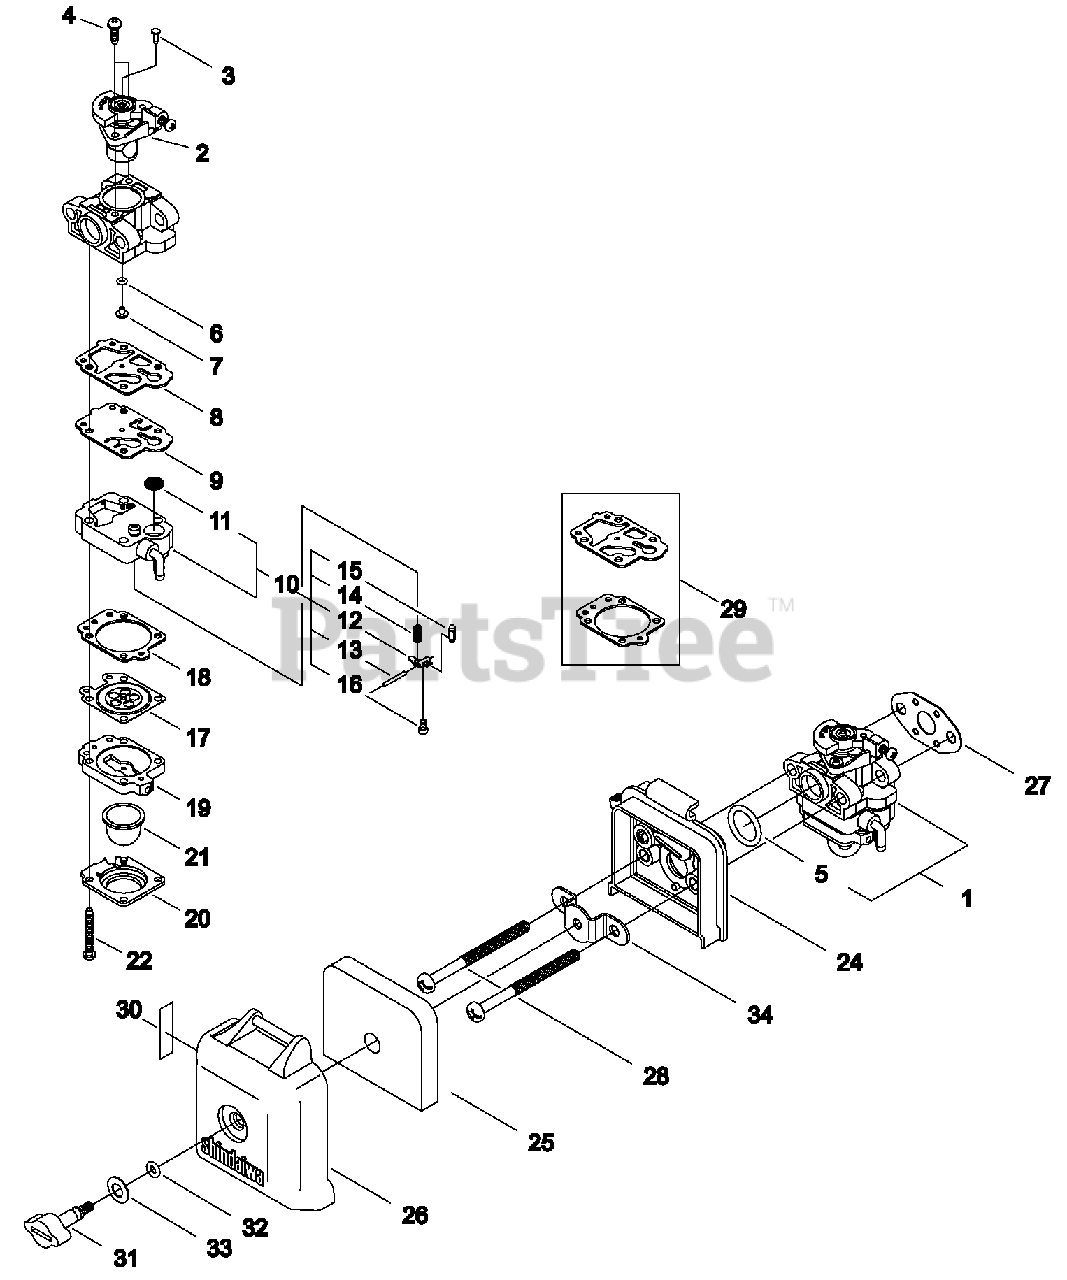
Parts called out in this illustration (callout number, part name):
1	CARBURETOR
2	VALVE ASSY, THROTTLE
3	PLUG
4	SCREW, THROTTLE COLLAR
5	O-RING 15
6	O-RING
7	JET, MAIN #40
8	GASKET, PUMP
9	DIAPHRAGM, FUEL PUMP
10	BODY ASSY, PUMP
11	SCREEN, FUEL INLET
12	LEVER, METERING
13	PIN, METERING LEVER
14	SPRING, METERING LEVER
15	VALVE, INLET NEEDLE
16	SCREW
17	DIAPHRAGM, METERING
18	GASKET, METERING DIAPHRAGM
19	BODY ASSY, PURGE
20	RETAINER, PURGE BULB
21	BULB, PURGE
22	SCREW
24	CASE, AIR FILTER
25	FILTER, AIR
26	COVER, AIR FILTER
27	GASKET, CARBURETOR
28	SCREW M5×60
29	GASKET KIT
30	LABEL, CHOKE
31	THUMBSCREW
32	O-RING
33	WASHER, CONE M6
34	BRACKET
